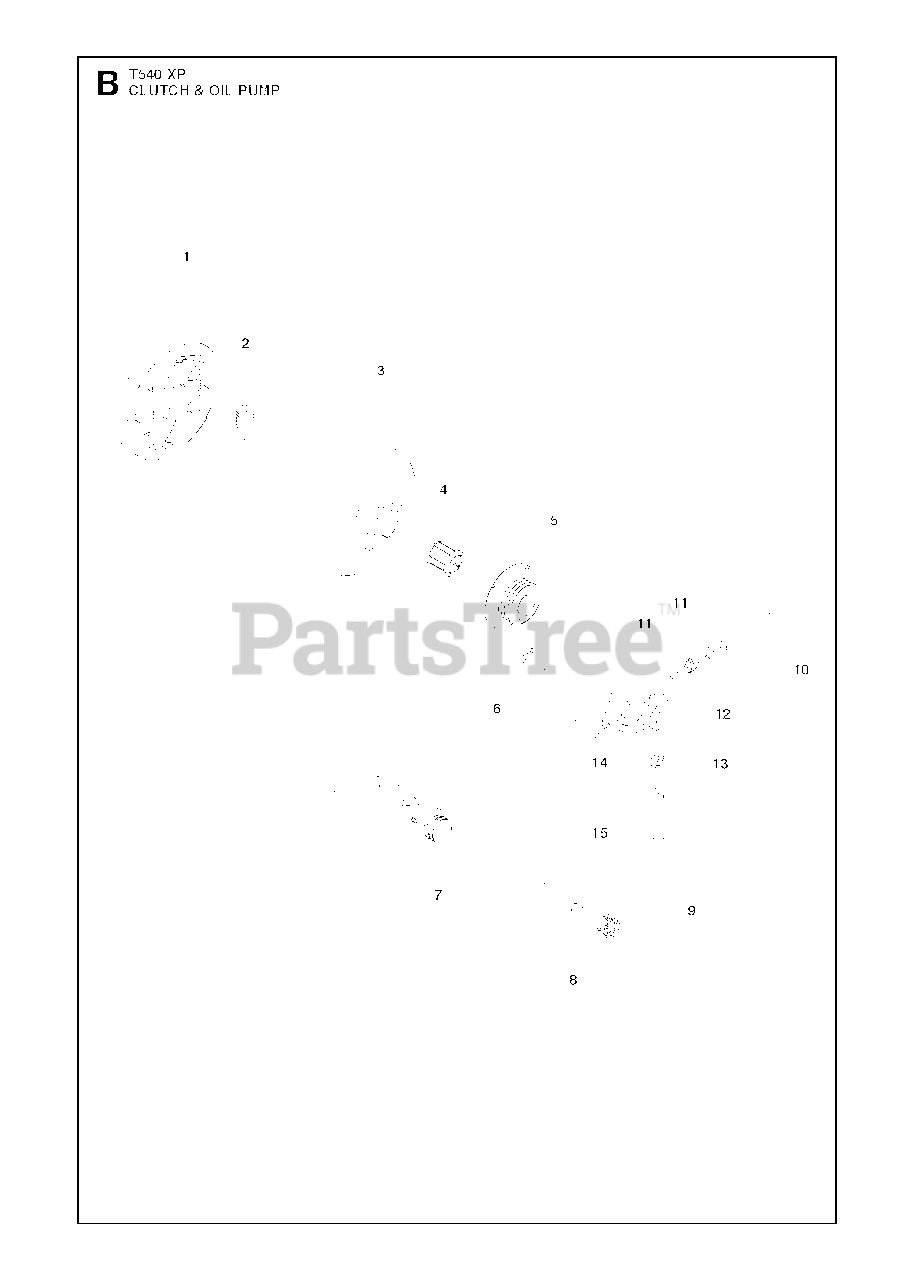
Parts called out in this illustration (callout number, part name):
1	CLUTCH ASSY
2	CLUTCH SPRING
3	CLUTCH DRUM ASSY KIT
4	NEEDLE BEARING
5	WORM WHEEL
6	SCREW ITXSCT
8	OIL PLUMMET
9	OIL PUMP ASSY
10	PUMP PISTON
11	WASHER
12	SPRING
13	PIN
14	SPRING
15	ADJUSTER
